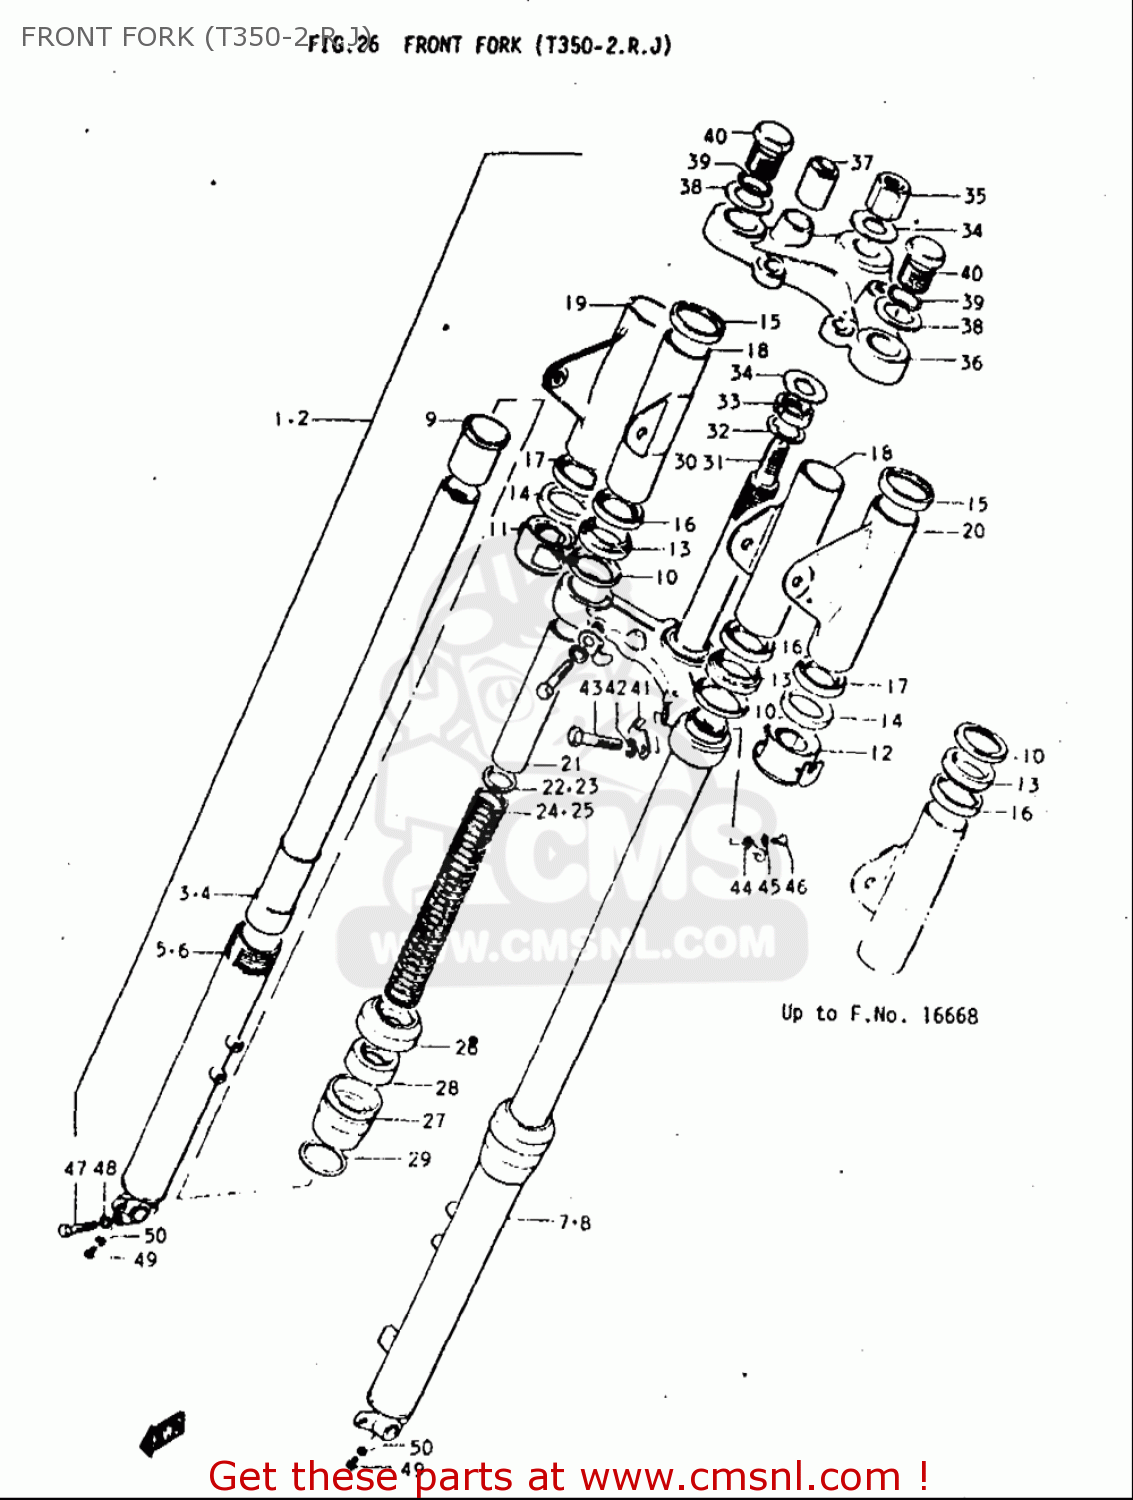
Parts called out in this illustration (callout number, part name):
3	TUBE,FORK,INNER
13	CUSHION,HEADLAMP BRACKET
14	CUSHION,HEADLAMP BRACKET
23	GUIDE,SPRING COVER
28	SEAL,OIL
35	NUT
39	O-RING,FORK FITTING BOLT
41	CLIP,SPEEDOMETER CABLE
42	WASHER,LOCK
44	CLIP,BRAKE CABLE
45	WASHER,LOCK
48	WASHER,LOCK
50	GASKET,DRAIN,PLUG (NAS)
